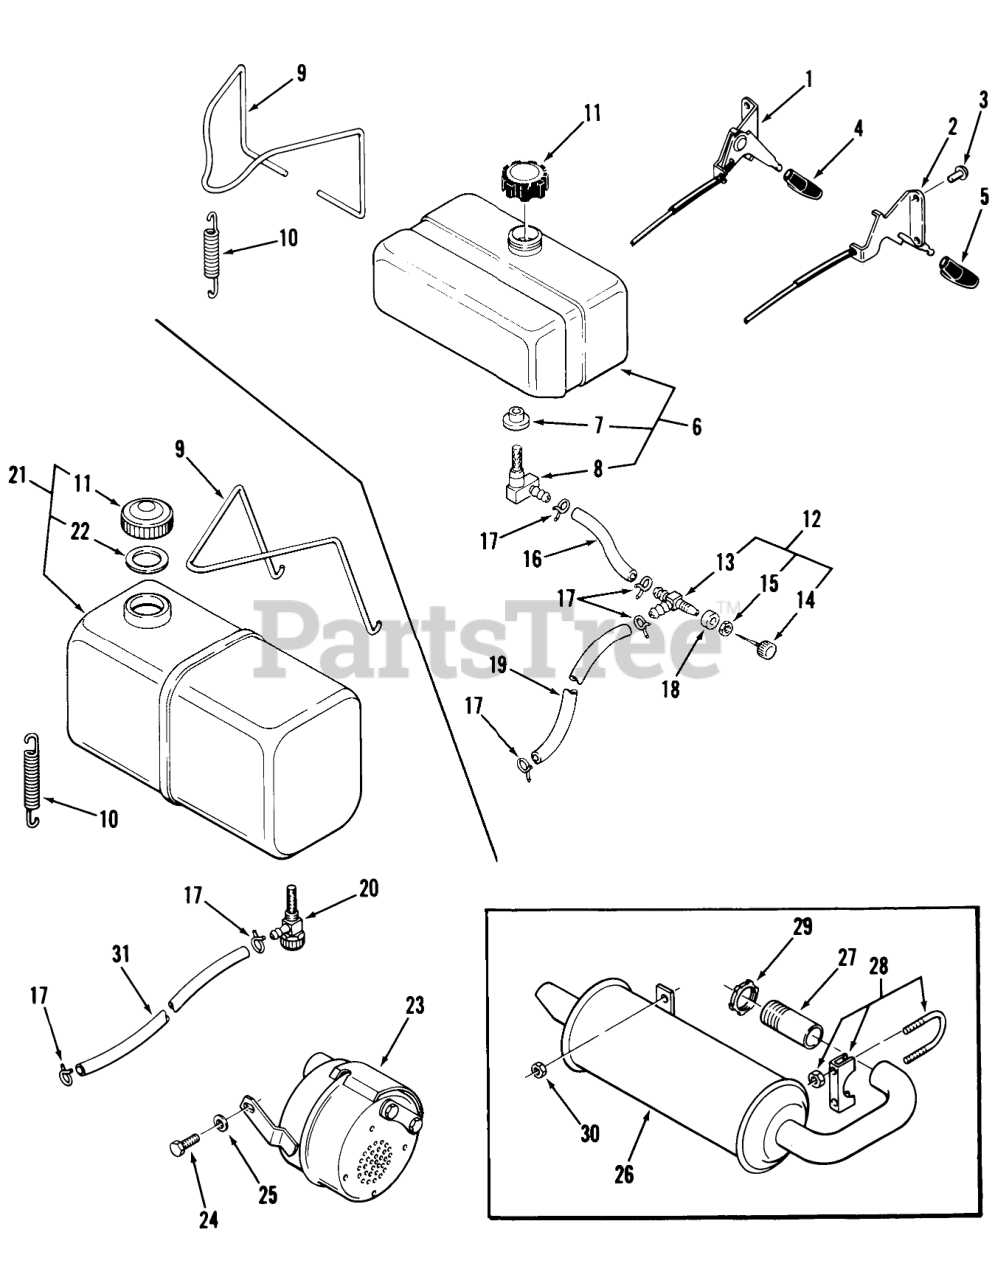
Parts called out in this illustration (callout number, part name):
1	CONTROL-THROTTLE
1	Throttle Control
2	CONTROL-CHOKE
2	CONTROL THROTTLE
3	RIVET-4
4	KNOB-THROTTLE
5	KNOB-CHOKE
6	ASSY-FUEL TANK
7	BUSHING
8	FITTING FUEL TANK
9	WIRE-HOLD DOWN
9	Hold Down Wire
10	SPRING-EXTENSION
11	Gasoline Cap
11	CAP-GASOLINE
12	S/A FUEL VALVE
13	VALVE BODY
14	STEM
15	NUT
16	Fuel Hose 3.8 in. (9.7 cm)
17	Clamp
18	SPACER
19	Fuel Hose 18"
20	FILTER & VALVE ASSY
21	Fuel Tank Assy
22	Seal (Service Only)
23	ASSY-MUFFLER
24	Bolt
26	Muffler
27	NIPPLE
28	ASSY-MUFFLER CLAMP
29	Lock Nut
30	Flanged Nut
31	Fuel Hose 25.4 in. (64.6 Cm) B-165 Only
31	Fuel Hose 18"
